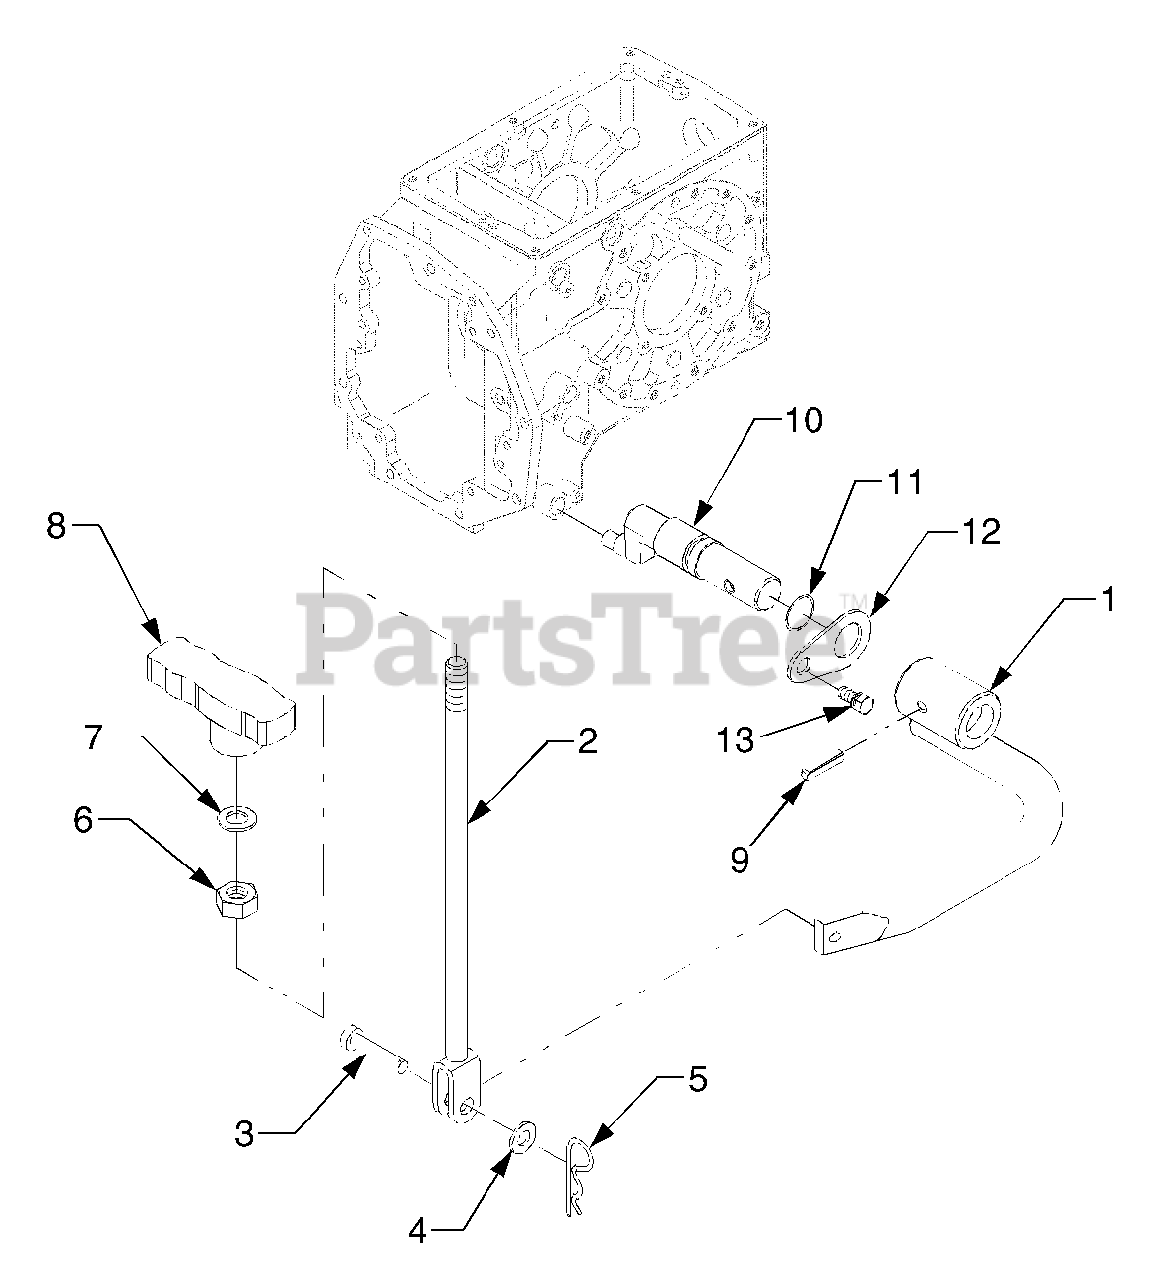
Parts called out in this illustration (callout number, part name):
1	Lever 1, Front Wheel
2	Lever 2, Front Wheel
4	Washer, Plain
7	Washer, Plain
8	Grip
